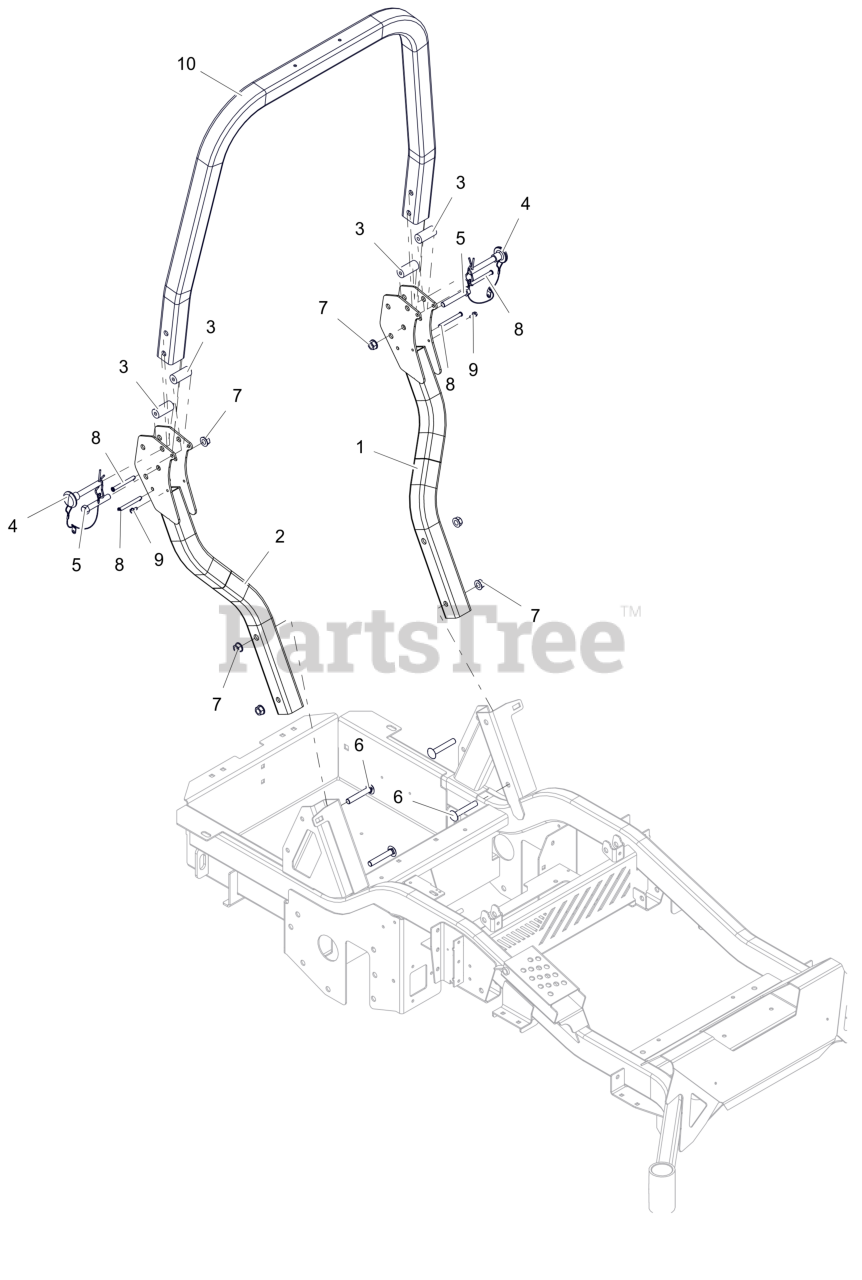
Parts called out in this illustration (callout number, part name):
1	WLDMT, LH ROPS LOWER
2	WLDMT, RH ROPS LOWER
3	BUMPER, ROPS ANTI-VIBRATION
4	PIN, ROPS W/LANYARD
5	BLT, HEX .50-13X3.00 G5 ZCC
6	BTL,RHSSN .500-13 X 3 G5 ZCC
7	NUT-LK-CTR-FLG .500-13 GG ZCC
8	PIN, SLIC .312 X 2.57
9	SCR-TAP .25-20X.50 HWH ZCC
10	TUBE, ROPS UPPER HOOP
